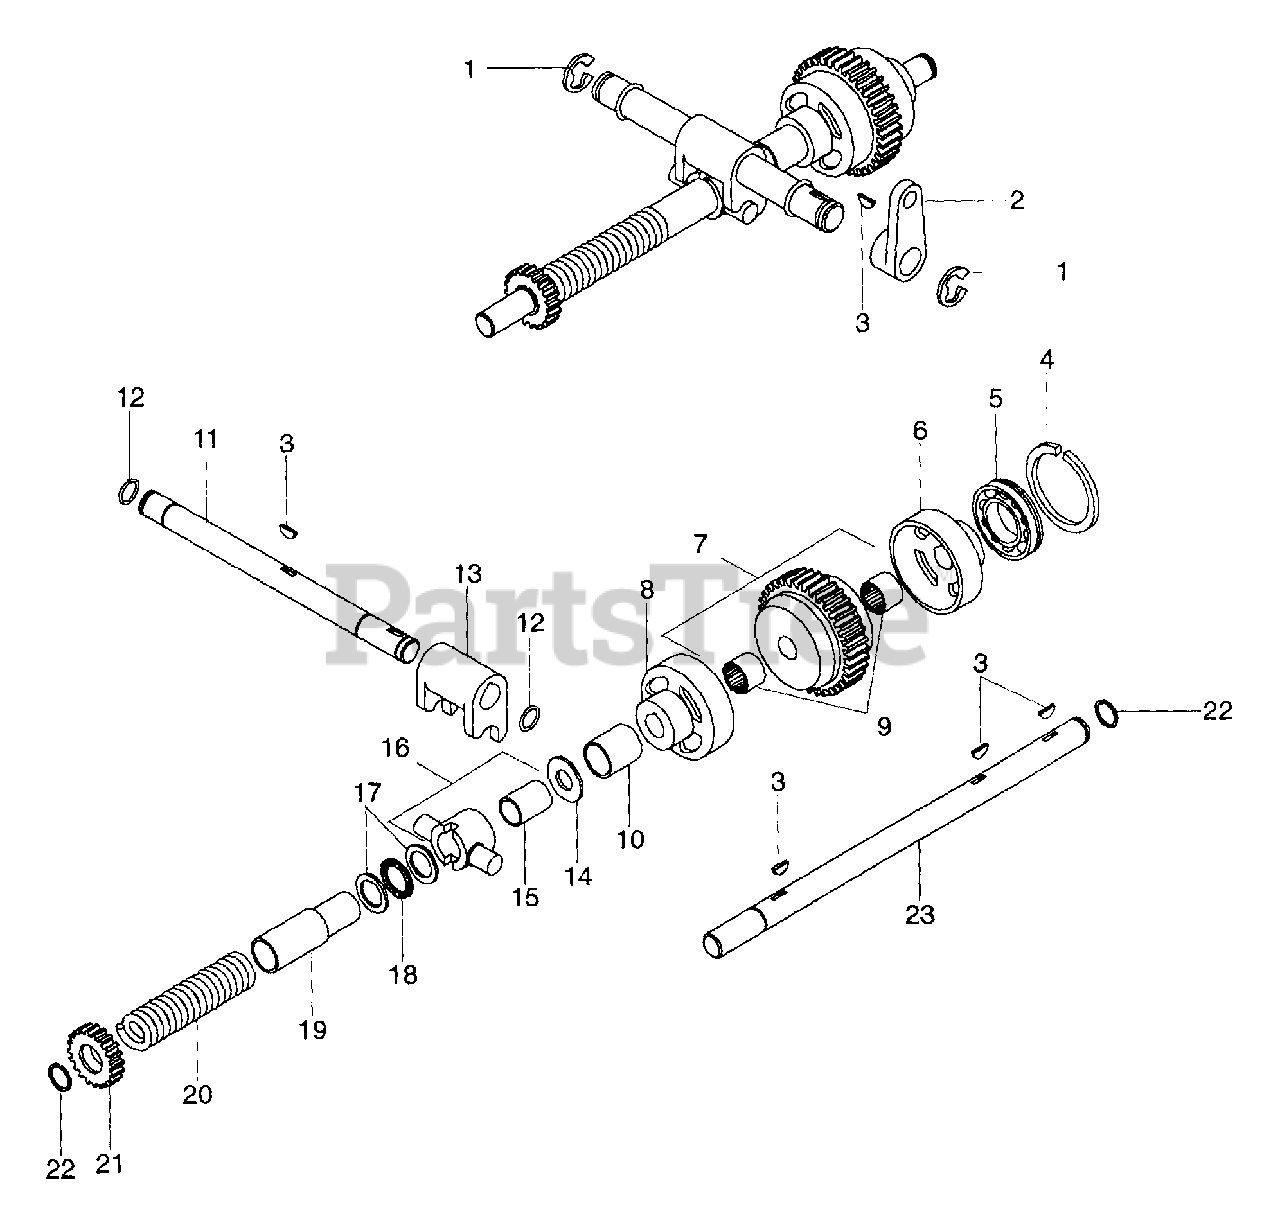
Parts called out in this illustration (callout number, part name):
1	Ring-Retaining-External .574 x .050
2	Lever, PTO
3	key, Woodruff .19 x .75
4	Ring-Retaining-External 1.38 x 1.304
5	Bearing-Ball 1.38 x 2.44 x .55
6	Cup, Clutch
7	Assembly, Clutch Cone Bearing
8	Cup, Clutch
9	Bearing, Roller .75 x 1.0 x .50
10	Bushing-Sleeve .891 x 1.00 x 1.21
11	Shaft, PTO Yoke
12	O-Ring .625 x .75 x .062
13	Yoke, PTO
14	Bearing-N-Thrust .752 x 1.24 x .093
15	Bushing-Sleeve 1.000 x 1.120 x 1.000
16	Shifting Collar Assy
17	Washer-Thrust 1.55 x 1.002 x .093
18	Bearing-N-Thrust 1.0 x 1.55 x .078
19	Sleeve, PTO Throw Out
20	Spring-Compression .187 x 5.50
21	Gear, Spur PTO 10 DP 22 T
22	Ring-Retaining .697 x .93
23	Shaft, PTO Clutch
